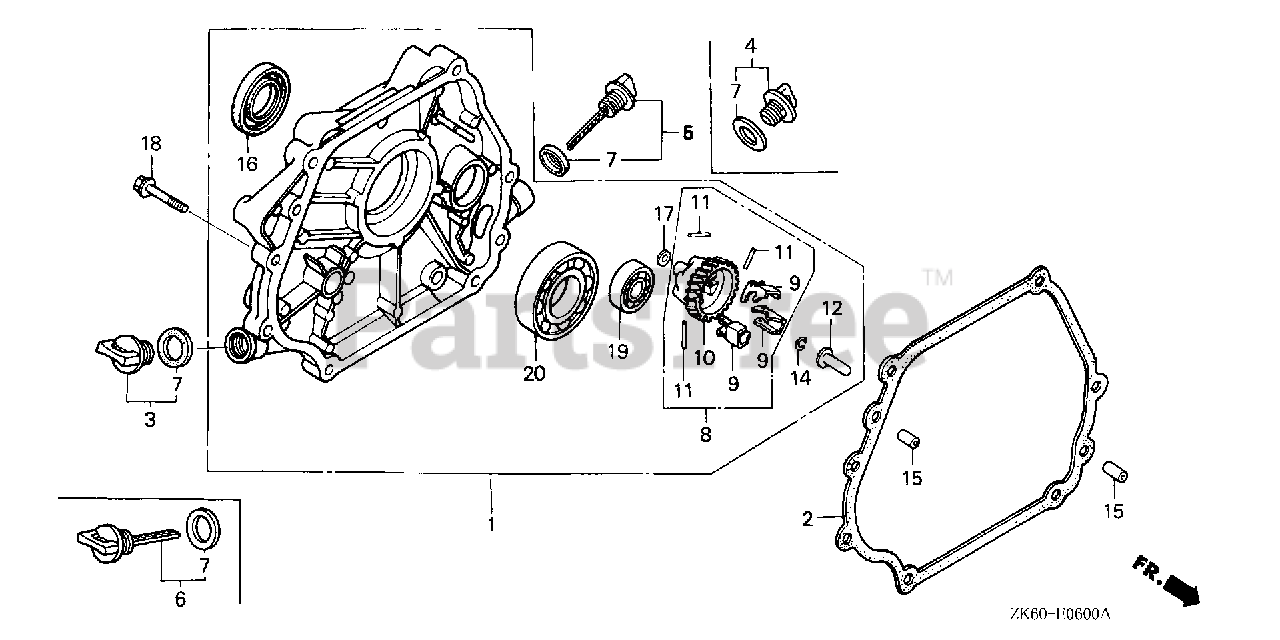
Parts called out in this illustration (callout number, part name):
1	COVER ASSY., CRANKCASE
2	GASKET, CASE COVER
3	CAP ASSY., OIL FILLER
5	CAP ASSY., OIL FILLER
7	GASKET, OIL FILLER CAP
8	GOVERNOR ASSY.
9	WEIGHT, GOVERNOR
10	HOLDER, GOVERNOR WEIGHT
11	PIN, GOVERNOR WEIGHT
12	SLIDER, GOVERNOR
14	CLIP, GOVERNOR HOLDER
15	PIN, DOWEL (8X12)
16	OIL SEAL (35X52X8)
17	WASHER, PLAIN (6MM)
18	BOLT, FLANGE (8X40)
19	BEARING, RADIAL BALL (6202)
20	BEARING, RADIAL BALL (6207)
